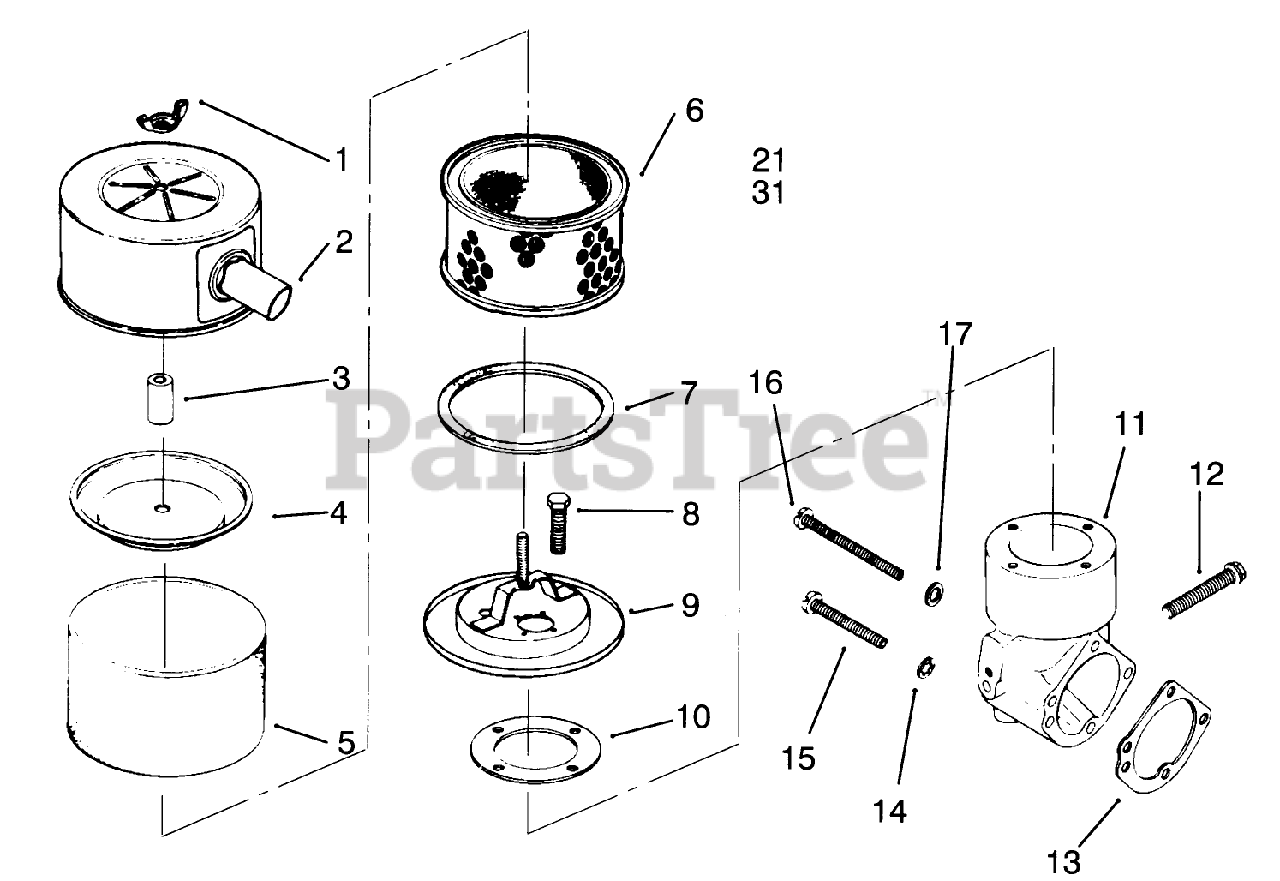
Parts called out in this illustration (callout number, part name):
1	Nut-Wing
2	Cover-Air Cleaner
3	Seal
4	Cover-Inner
5	Element
6	Element
7	Seal
8	Screw-H.C.
9	Base-Air Cleaner
10	Gasket-Air Cleaner
11	Kit-Elbow (Incl. Ref. #12 & 13)
12	Screw-H.C
13	Gasket-Elbow
14	Washer
15	Screw-R.H.M.
16	Screw-R.H.M.
17	Washer
